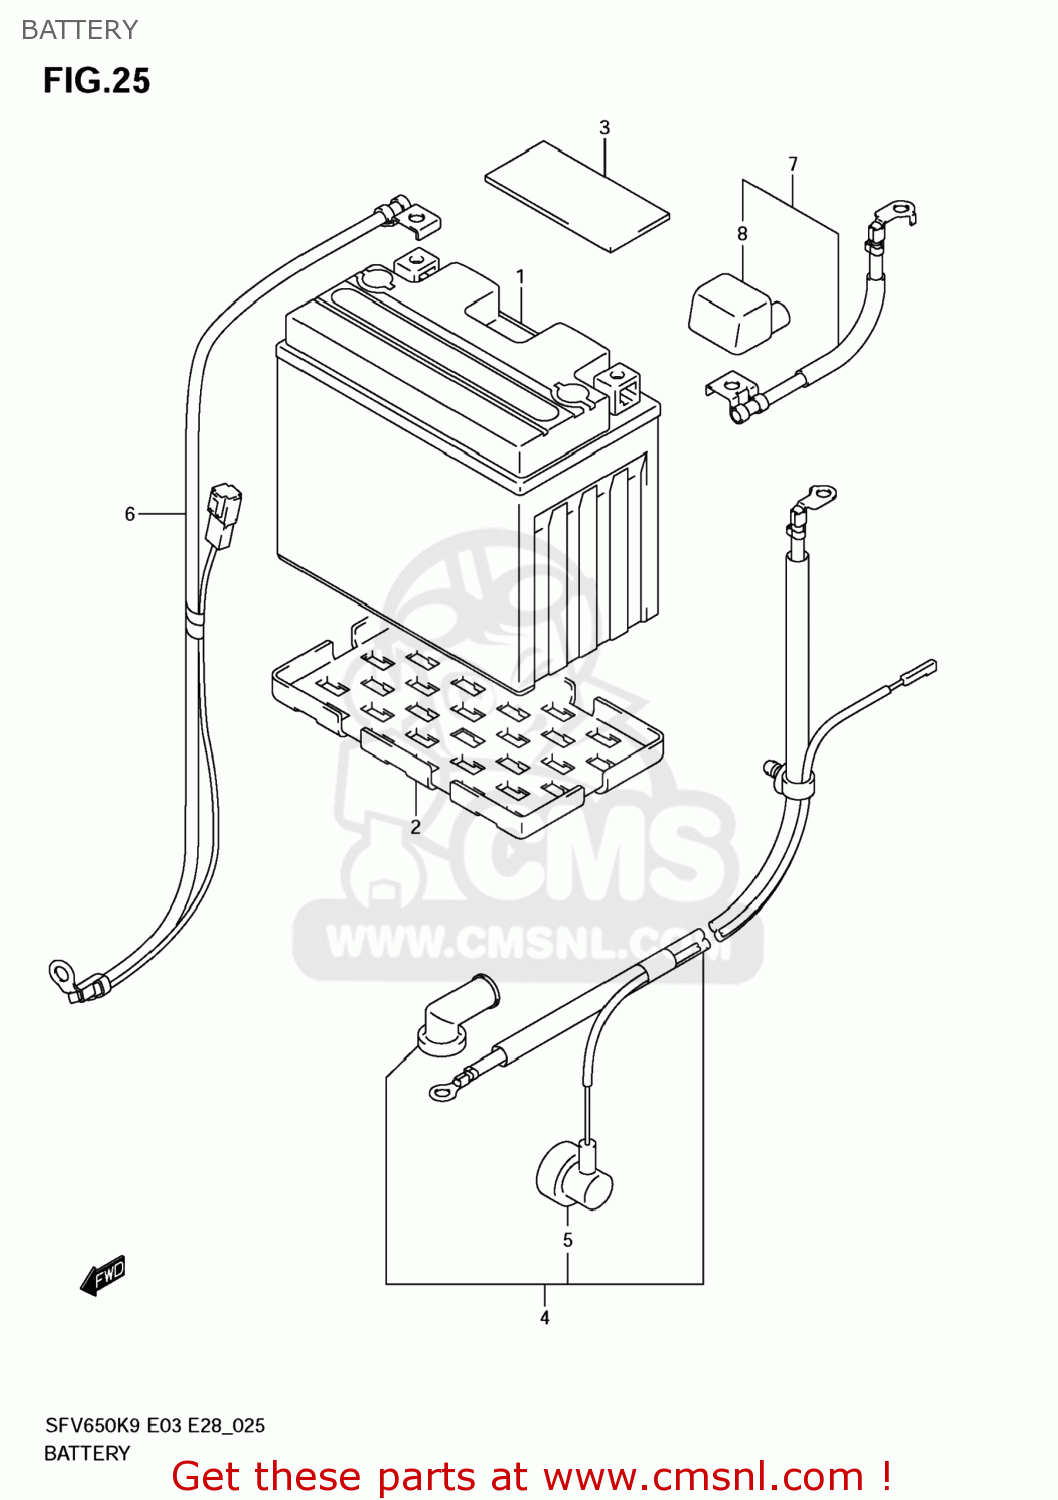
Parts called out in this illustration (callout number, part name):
1	BATTERY(YT12A-BS,12V10.5AH)
2	PROTECTOR,BATTERY
3	PROTECTOR
4	WIRE,STARTER MOTOR LEAD
5	CAP,OIL PRESSURE SWITCH
6	WIRE,BATTERY MINUS LEAD
7	WIRE,BATTERY PLUS LEAD
8	CAP,BATTERY PLUS
